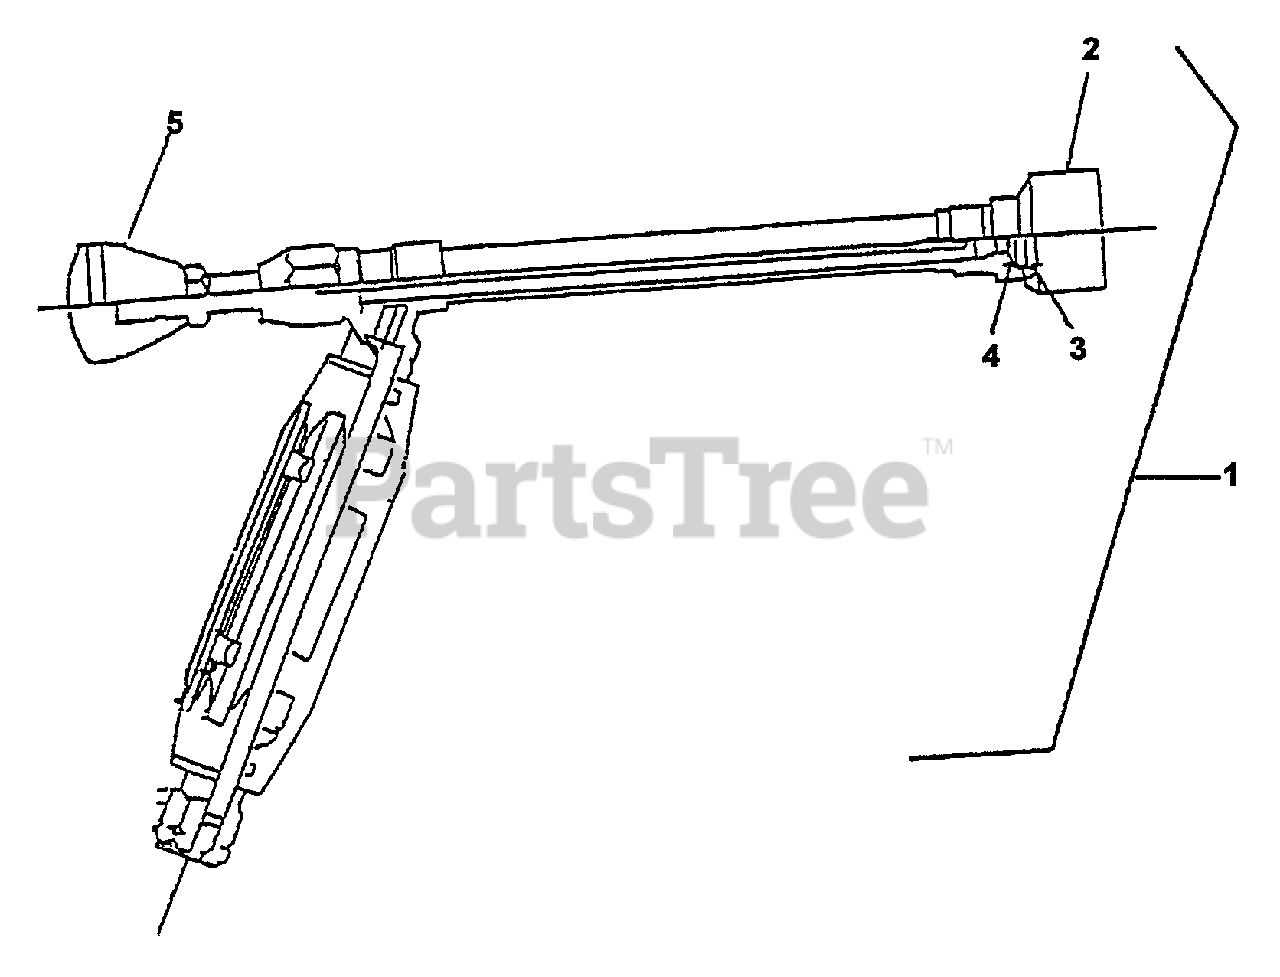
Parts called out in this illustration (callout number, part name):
1	ADJUSTABLE JET NOZZLE
2	CAP, NOZZLE
3	PLATE, NOZZLE
4	GASKET, NOZZLE
5	KNOB
